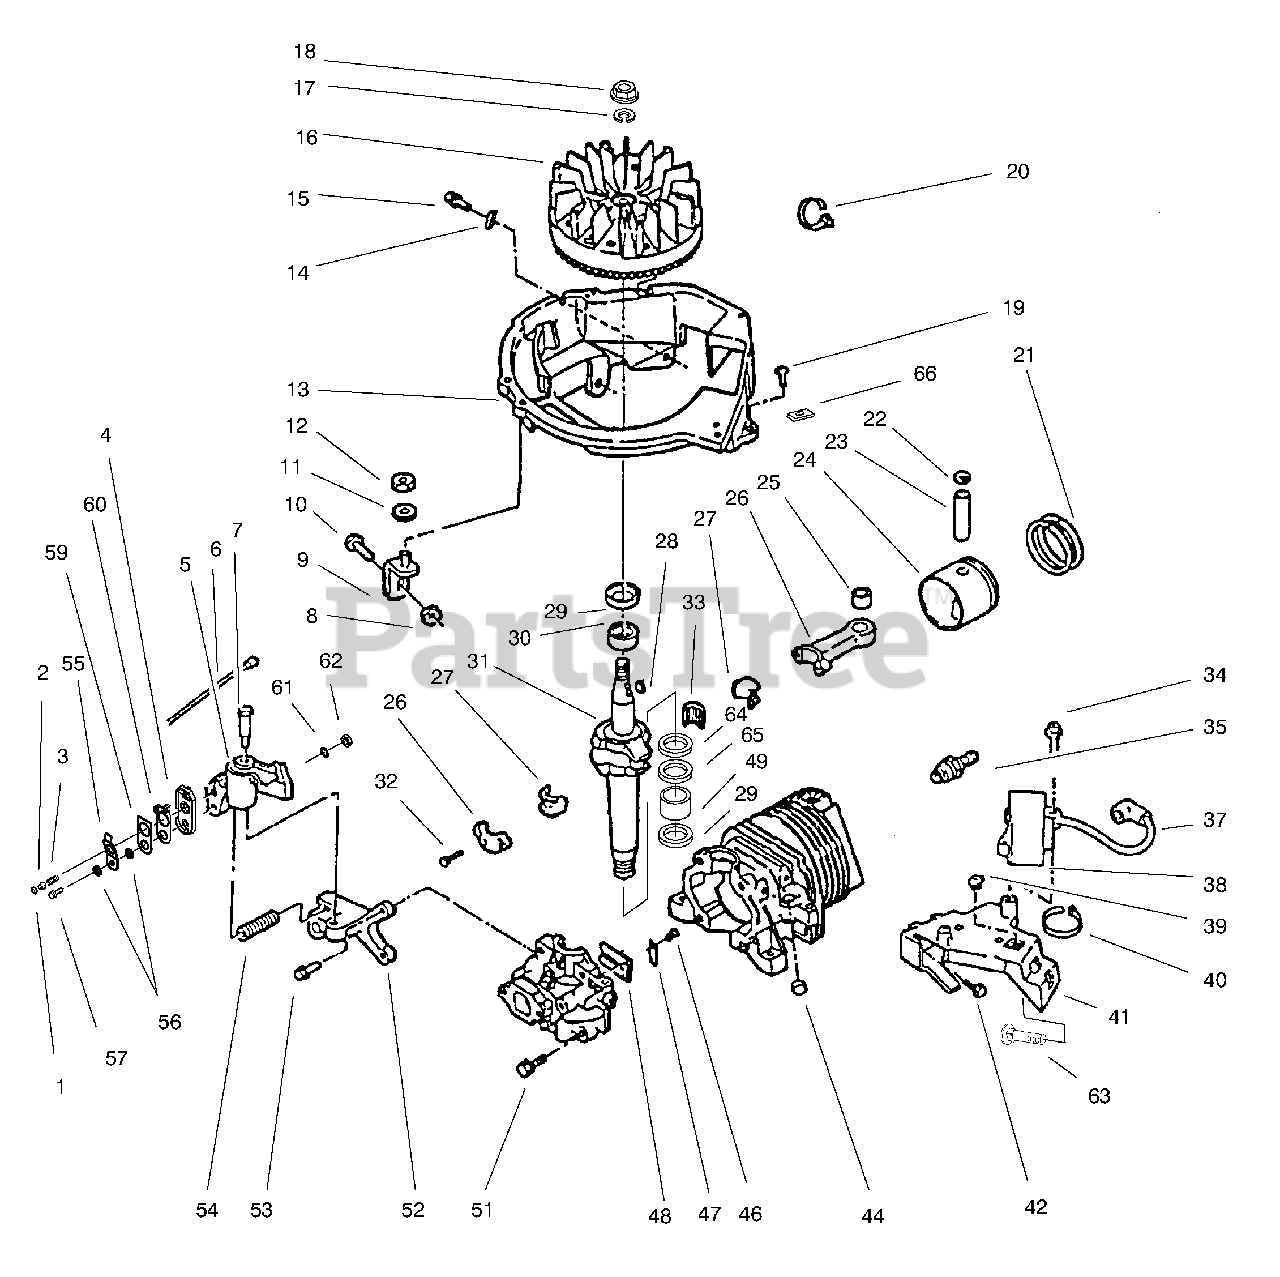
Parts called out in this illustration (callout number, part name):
1	Retainer
2	Actuator-Brake Lever
3	Spring-Cable, Return
4	Case-Switch
5	Assembly-Brake
6	Wire Lead
7	Bolt-Shoulder
9	Assembly-Brace
11	Washer
13	Shroud-Base
14	Clip-"J"
16	Assembly-Flywheel
17	Washer-Lock
18	Nut-Flywheel
20	Tie Strap
21	Set-Ring
22	Ring-Retaining
23	Pin-Wrist
24	Set-Piston & Ring (Incl. Ref.# 21-23)
25	Assembly-Bearing
26	Assembly-Conn. Rod (Incl. Ref. #25, 27, 32, & 33)
27	Liner-Pair
28	Key-Flywheel
29	Seal-Oil
30	Bearing-Main
31	Crankshaft
33	Strip-Roller
34	Screw
35	Spark Plug
37	Wire Lead
38	C. D. Ignition Module (Incl. Ref. #37)
39	Grommet
40	Tie Strap
41	Bracket-C. D.
47	Plate-Reed
49	Bearing-Main
52	Bracket-Brake
54	Spring-Brake
56	Washer
57	Screw-Hex Hd. Cap
60	Plate-Contact
61	Washer-Lock
62	Nut
63	Bolt-Carriage
64	Bearing-Thrust
65	Washer-Thrust
66	Nut-Speed
